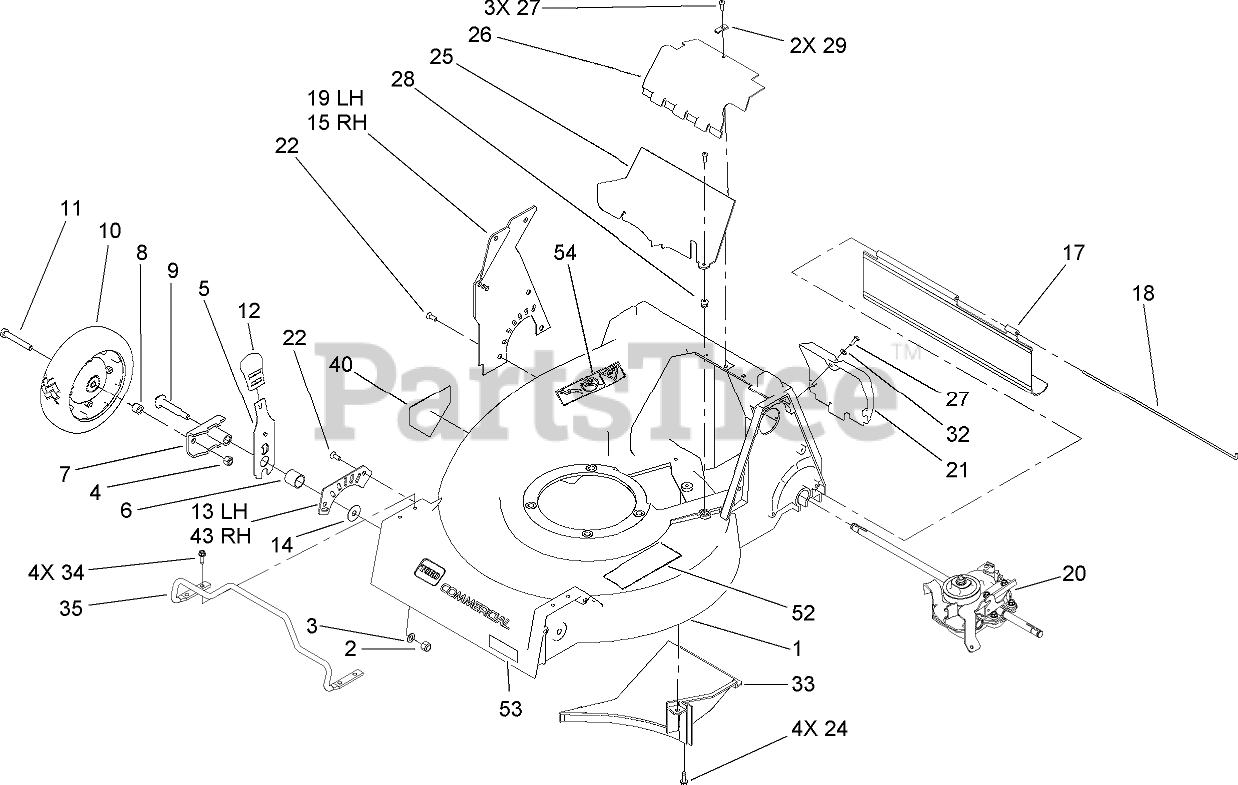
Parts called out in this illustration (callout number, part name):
1	HOUSING
2	NUT-LOCK
3	WASHER
4	NUT-LOCK, CONE
5	SPRING ARM ASM
6	SPACER-BEARING
7	ARM-PIVOT, FRONT
8	SPACER-WHEEL
9	BOLT-WHEEL
10	Wheel and Tire ASM
11	SCREW-HH
12	KNOB-HOC
14	WASHER-PLAIN
15	PLATE-REAR HOC, RH
17	SHEILD-TRAILING
18	ROD-SHIELD
20	GEAR CASE ASM
21	DOOR-ACCESS, REAR
22	SCREW-HH
24	SCREW-HWHTF
25	COVER-BELT, LOWER
26	COVER-BELT, UPPER
28	NUT-CLIP
29	NUT-TYPE J
32	WASHER-FLAT
33	BAFFLE-CHUTE, FLOOR
34	SCREW-HWHTF
35	GUARD-ENGINE
40	DECAL-DANGER
43	PLATE-FRONT HOC, RH
52	DECAL-WARNING
53	DECAL-BLADE
54	DECAL-DANGER
